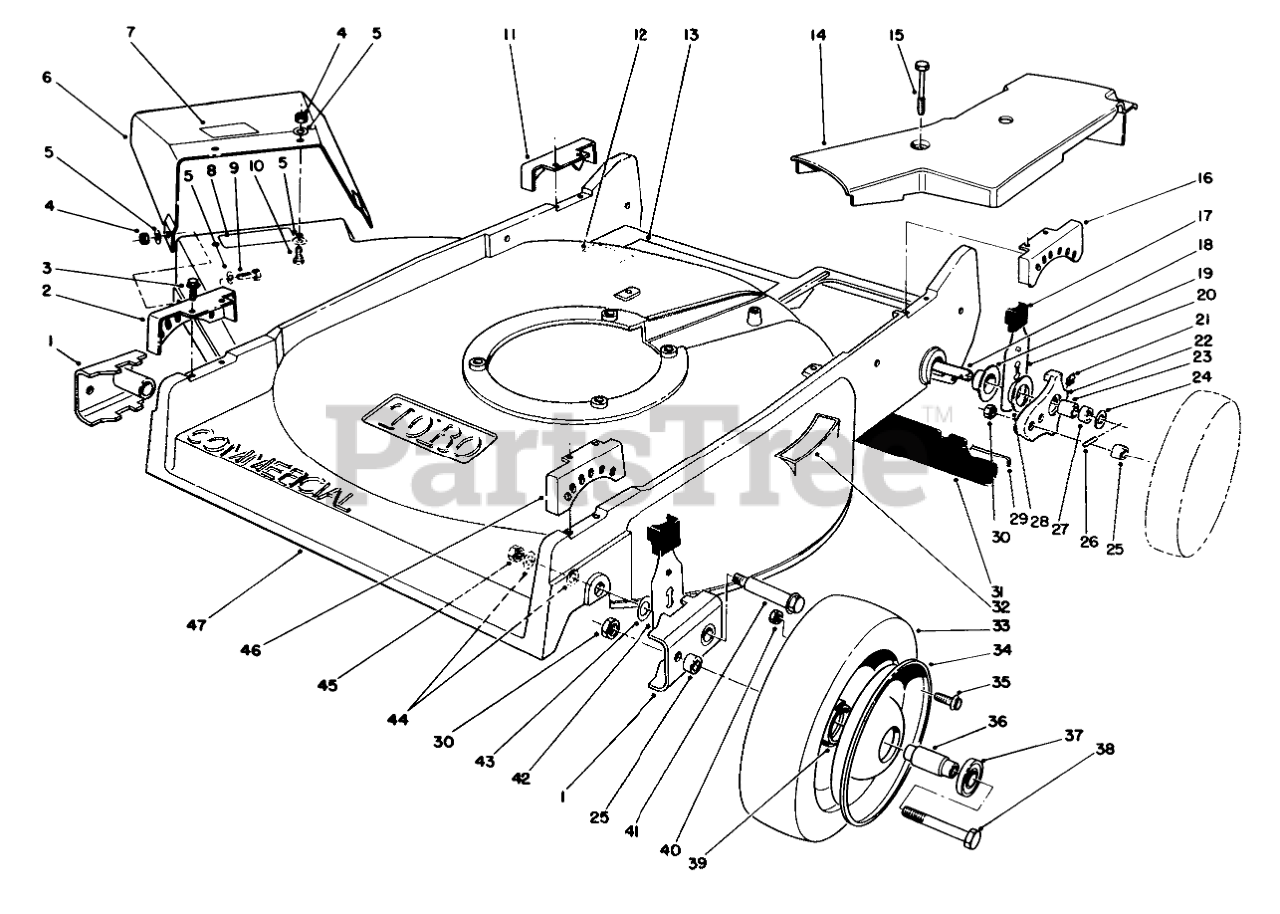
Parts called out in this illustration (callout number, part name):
1	ARM-PIVOT, FRONT
2	QUADRANT-FRONT, RH
3	SCREW-HWHTF
5	WASHER-FLAT
6	Deflector Assy. (Incl. Ref. #7)
7	Decal Danger
8	DECAL - WARNING/INT'L
9	SCREW-HH
10	SCREW-HH
11	QUADRANT-REAR, RH
12	Decal
13	Decal-Safety Instructions
14	COVER-BELT
15	SCREW-HHFTF
16	QUADRANT-REAR, LH
17	KNOB-ARM
18	SHAFT-AXLE, REAR
19	CAP-END
20	REAR SPRING ARM ASM
21	FITTING-GREASE
22	Pivot Arm Assembly (Rear)(Incl. Ref. #21, 23 & 27)
23	BUSHING
24	WASHER-PLAIN
25	SPACER-WHEEL
26	PIN-SPIROL
27	BUSHING
28	WASHER
29	ROD-SHIELD
30	NUT-LOCK, CONE
31	SHIELD-TRAILING
32	DECAL - STEP PAD INT'L
34	Wheel-Half
35	SCREW-HHF
36	SPACER-BEARING
37	BEARING-WHEEL
38	SCREW-HH
39	HUB-BEARING
40	NUT-LOCK, NI
41	WHEEL BOLT
42	FRONT SPRING ARM ASM
43	WASHER-THRUST
44	WASHER
45	Nut
46	QUADRANT-FRONT, LH
47	Housing-Commercial (Incl. Ref. #8, 13 & 32)
